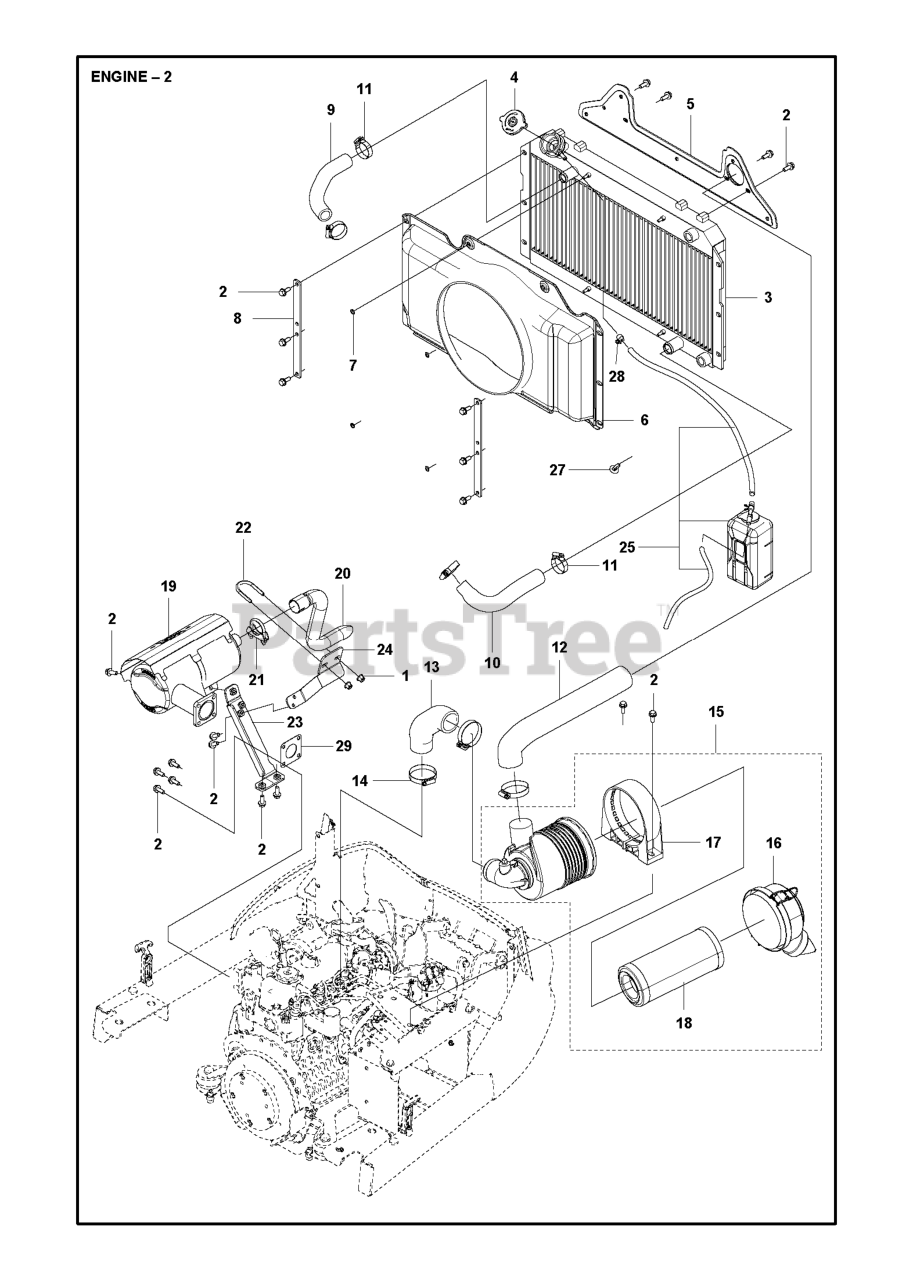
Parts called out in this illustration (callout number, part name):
1	NUT FLANGE
16	AIR FILTER END COVER
18	AIR FILTER
28	RP HOSE CLAMP FUEL HOSE
